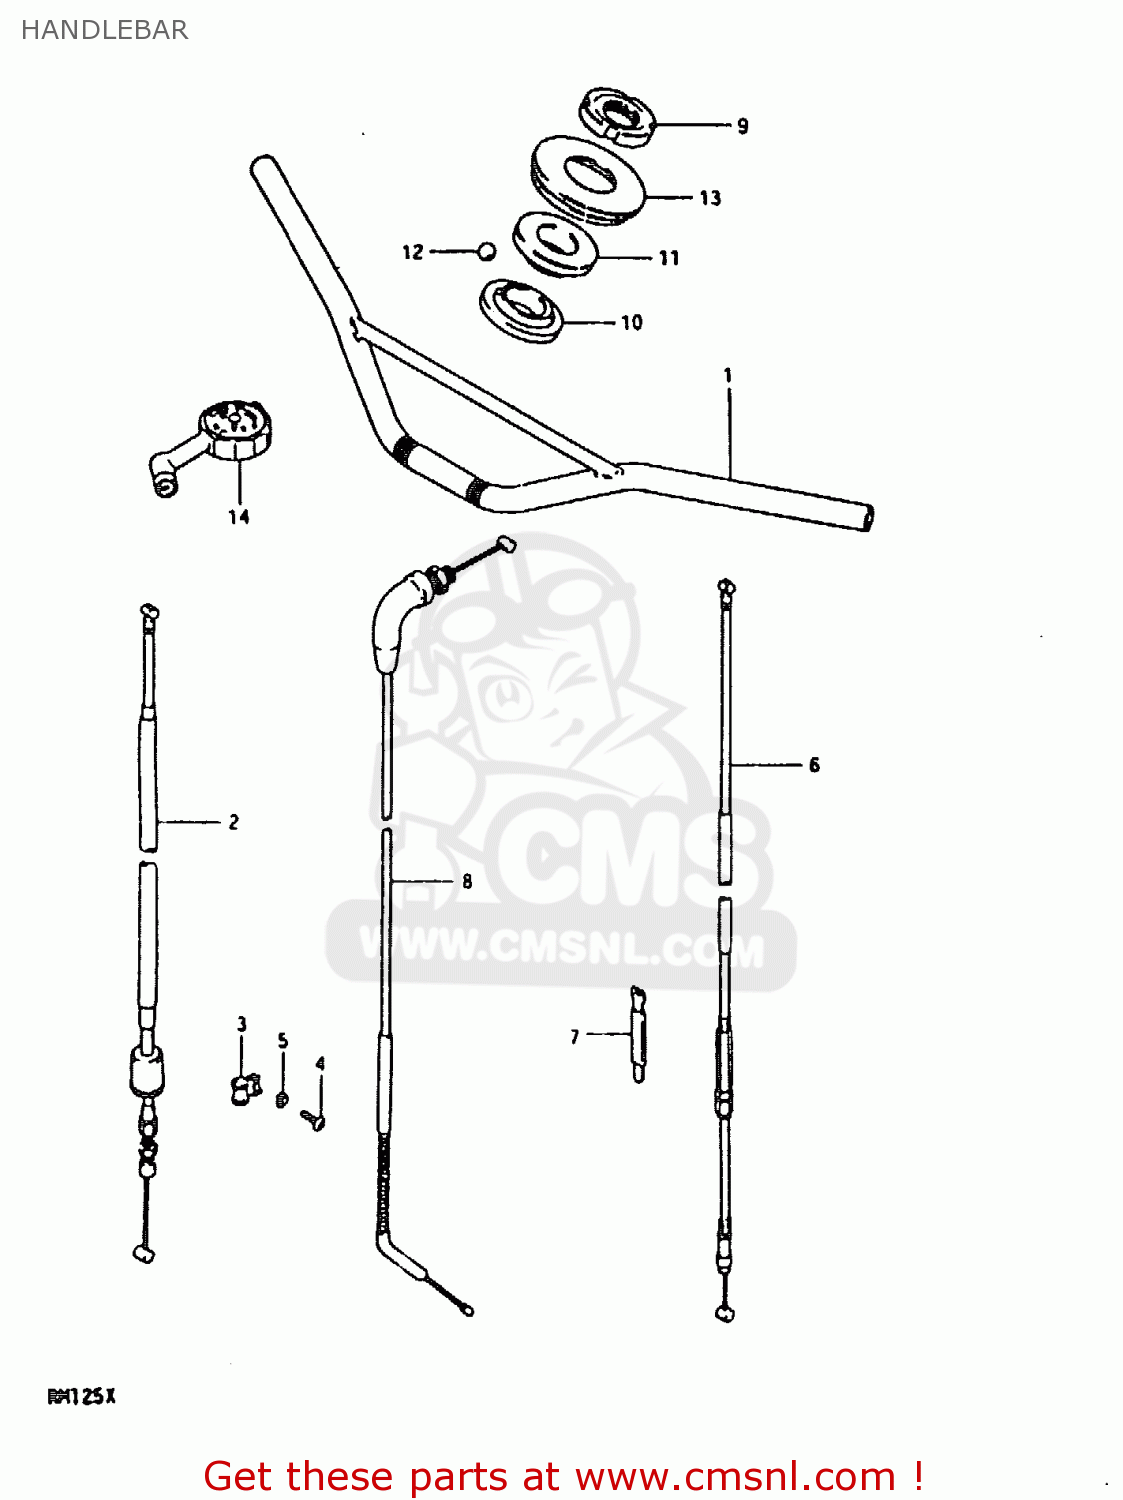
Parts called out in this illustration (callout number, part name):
1	HANDLEBAR
2	CABLE ASSEMBLY,FRONT BRAKE
3	GUIDE,CABLE
4	SCREW
5	LOCK WASHER
6	CABLE ASSEMBLY,CLUTCH
7	CLAMP
8	CABLE ASSEMBLY,THROTTLE
9	NUT,STEERING STEM
10	RACE,STEERING,INNER,UPPER
11	RACE,STEERING,OUTER,UPPER
12	BALL
13	SEAL,STEERING UPR DUST
14	GAUGE ASSY,AIR PRESSURE
